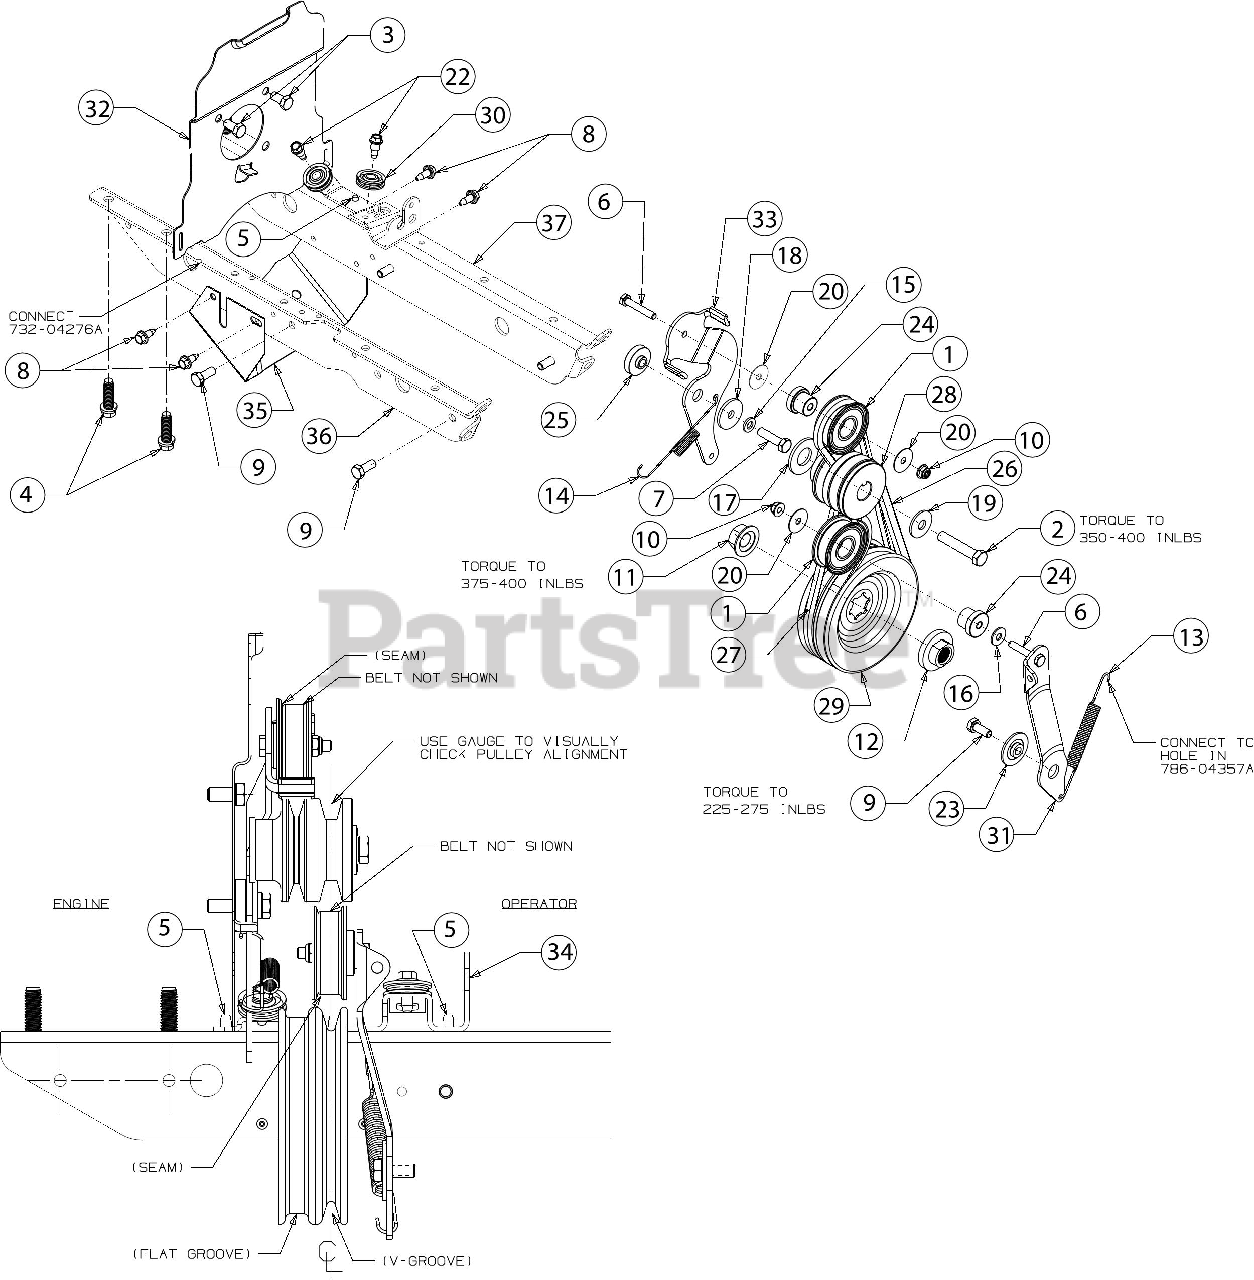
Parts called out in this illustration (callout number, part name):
1	IDLER PULLEY ASSEMBLY
1	BEARING SLEEVE
1	BALL BEARING
2	HEX SCREW 3/8-24 X2.00
3	HEX SCREW 5/16-24 X .62
4	SCREW 3/8-16 X 1.250
5	SCREW 1/4-20 X.500
6	SCREW 1/4-20 X 1.50 GR.5
7	SCREW 5/16-24 X 1.25 GR5
8	SCREW 1/4-14 X .625
9	SCREW 5/16-18 X .750
10	FLANGE LOCK NUT
11	FLANGE NUT W/HUB
12	PULLEY HUB
13	RETURN SPRING
14	EXTENSION SPRING
15	LOCK WASHER 5/16
16	FLAT WASHER .28 ID X .74 OD X .063
17	FLAT WASHER
18	WASHER-5/16 X 1.25X 1.27
19	BELL WASHER
20	FLAT WASHER
22	SHOULDER SCREW
23	PIVOT IDLER SPACER
24	SHOULDER SPACER
25	PIVOT IDLER SPACER
26	V-BELT FWD DRIVE 4L X 25.375
27	V-BELT REV DRIVE 3L X 29.125
28	ENGINE PULLEY
29	TRANSMISSION PULLEY
30	CABLE GUIDE ROLLER
31	FORWARD IDLER BRACKET
32	REVERSE IDLER BRACKET
33	REVERSE IDLER BRACKET
34	CABLE BRACKET ROLLER
35	PULLEY SHIELD
36	FRAME (LH)
37	FRAME (RH) 400/460/480/VTT
